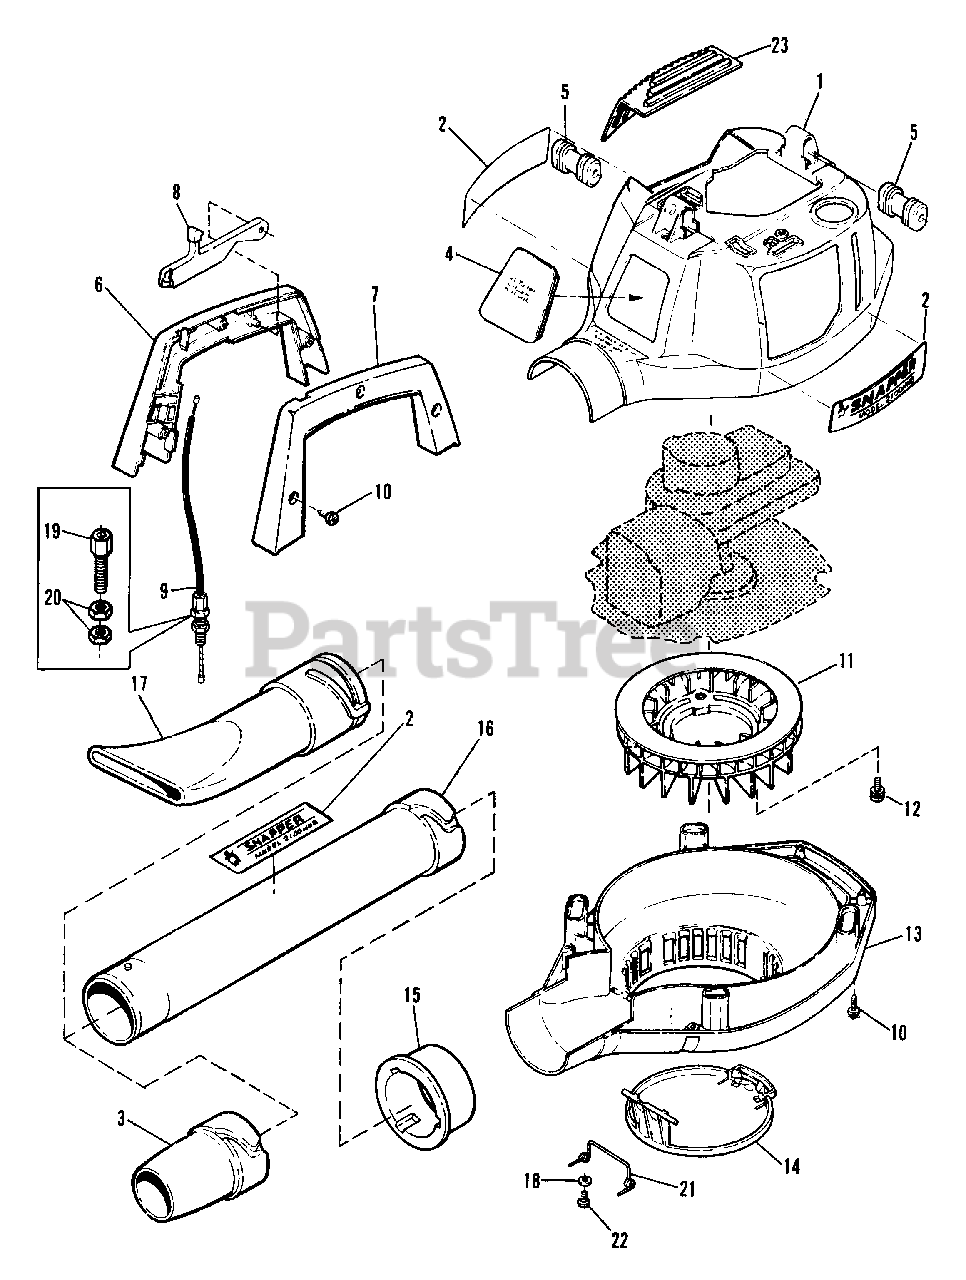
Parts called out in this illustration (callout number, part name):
1	HOUSING, Blower, Upper
2	DECAL, Snapper
3	NOZZLE, Tapered
4	COVER, Spark Plug
5	GROMMET, Handle Mounting
6	HANDLE, Right Side
7	HANDLE, Left Side
8	TRIGGER, Throttle
9	CABLE, Throttle
10	SCREW, M5 x 20mm Pan Head
11	FAN-WHEEL
12	SCREW, M5 x 12mm Pan Head
13	HOUSING, Blower, Lower
14	COVER, Lower
15	SLEEVE, Tube
17	NOZZLE, Flare
18	WASHER, M3
19	SCREW, Adjust
20	NUT, Hex, M6 x 1.0
21	SPRING
22	SCREW, M3
23	COVER, Muffler
